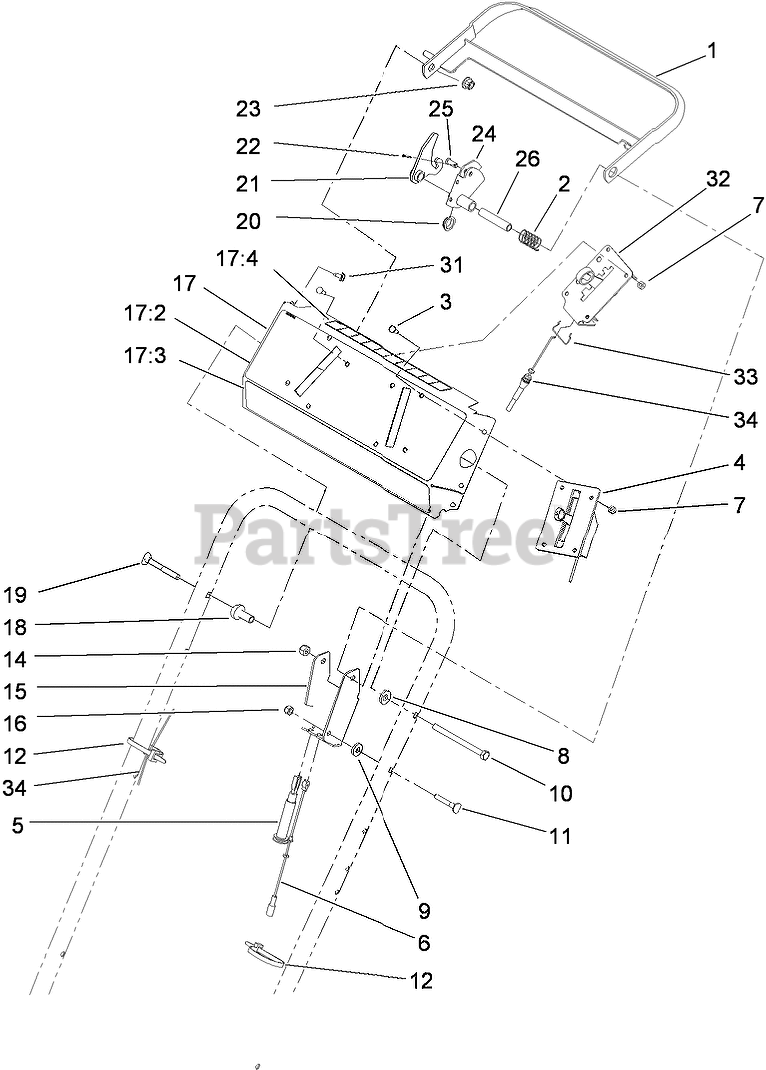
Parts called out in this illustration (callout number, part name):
1	BAR-CONTROL
2	SPRING-CONTROL
3	SCREW-PPH
4	CONTROL-THROTTLE
5	CABLE-TRACTION
6	CABLE-CLUTCH
7	NUT-LOCK, NI
8	SPACER
9	SPACER
10	SCREW-HH
11	SCREW-HANDLE
12	TIE-CABLE
14	NUT-LOCK, NI
15	BRACKET-CONTROL
16	NUT-LOCK, NI
17	PANEL ASM
17:2	DECAL-PANEL, CONTROL
17:3	Decal-Panel
17:4	DECAL-PANEL, REAR
18	SPACER-SUPPORT
19	SCREW
20	BUSHING-FLANGE
21	LEVER-TRACTION
22	PIN-COTTER
23	NUT-LOCK, NI
24	LEVER-BBC
25	PIN-CABLE
26	SPACER-BRACKET, CONTROL
31	SCREW-HWHTF
32	CONTROL-SHIFT
33	RETAINER-CABLE, THROTTLE
34	CABLE-SHIFT
